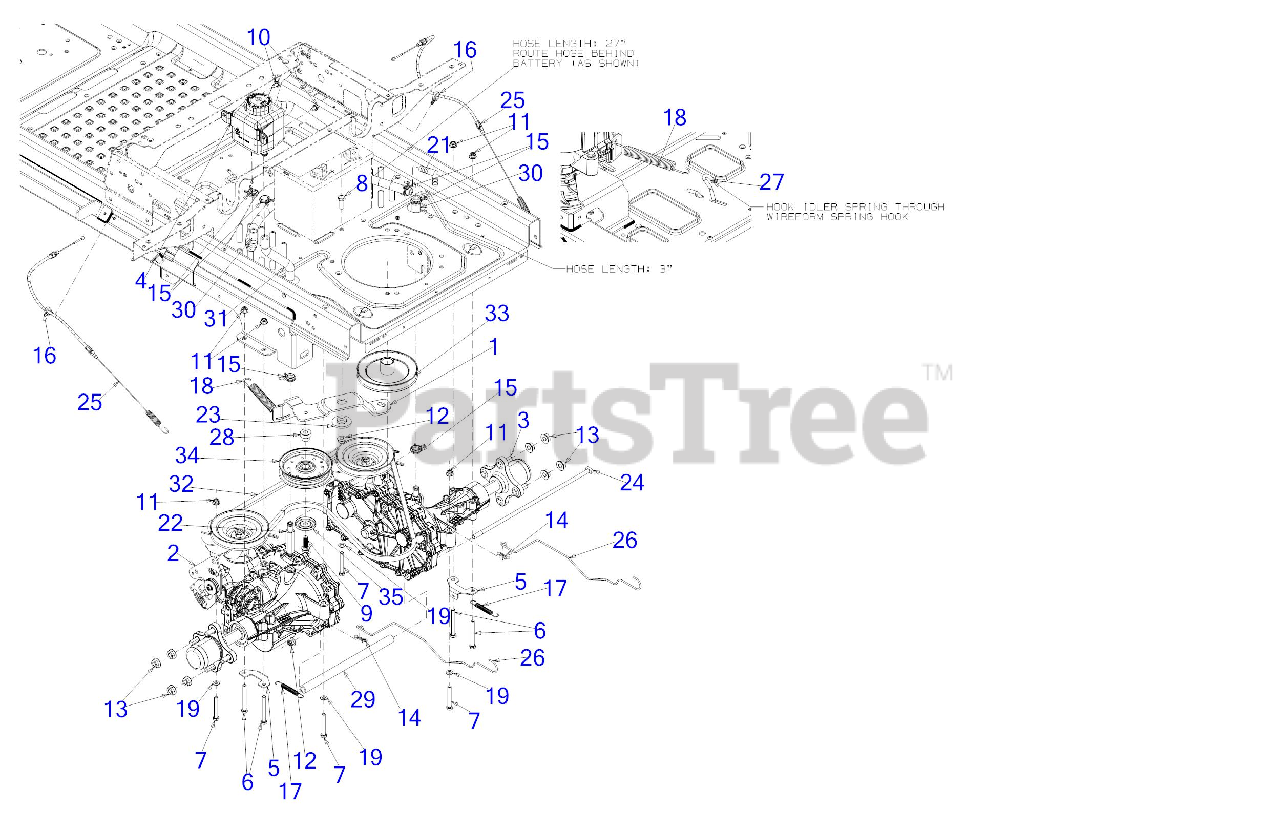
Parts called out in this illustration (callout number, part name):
1	IDLER BRACKET ASSEMBLY
2	TRANSMISSION ASSEMBLY (LH)
3	TRANSMISSION ASSEMBLY (RH)
4	HYDRAULIC TANK
6	HEX SCREW 5/16-18 x 2.75
7	HEX SCREW 5/16-18 x 2.25 GR5
8	SCREW 3/8-16 x 1 GR5
9	SCREW 3/8-16 X1.250
10	SCREW 1/4-20X.625
11	FLANGE LOCK NUT 5/16-18
13	HEX FLANGE NUT 7/16-14
14	BOW TIE COTTER PIN 1/4-5/16
15	FUEL HOSE CLAMP
16	CABLE RETAINER CLIP
17	EXTENSION SPRING .38 OD x 3.25 LG
18	EXTENTION SRING .75 DIA. x 6.85
19	FLAT WASHER
21	90 DEGREE NYLON FITTING
22	EXTENSION FITTING 9/16-18
23	SHOULDER SPACER
24	SUPPORT TUBE ROD
25	PARK BRAKE CABLE
26	HYDRO BYPASS ROD
27	IDLER SPRING HOOK
28	SHOULDER SPACER
29	TRANSMISSION SPACER .75OD x 11.31
30	FUEL LINE 1/2" ID
31	EXPANSION TANK HOSE
32	TRANSMISSION DRIVE BELT A x 67
32	Cub Cadet TRANS DRIVE BELT A x 67 RZT
32	Troy-Bilt TRANSMISSION DRIVE BELT
33	TRANMISSION DRIVE PULLEY
34	IDLER PULLEY 4.25 DIA
35	IDLER PULLEY CAP
